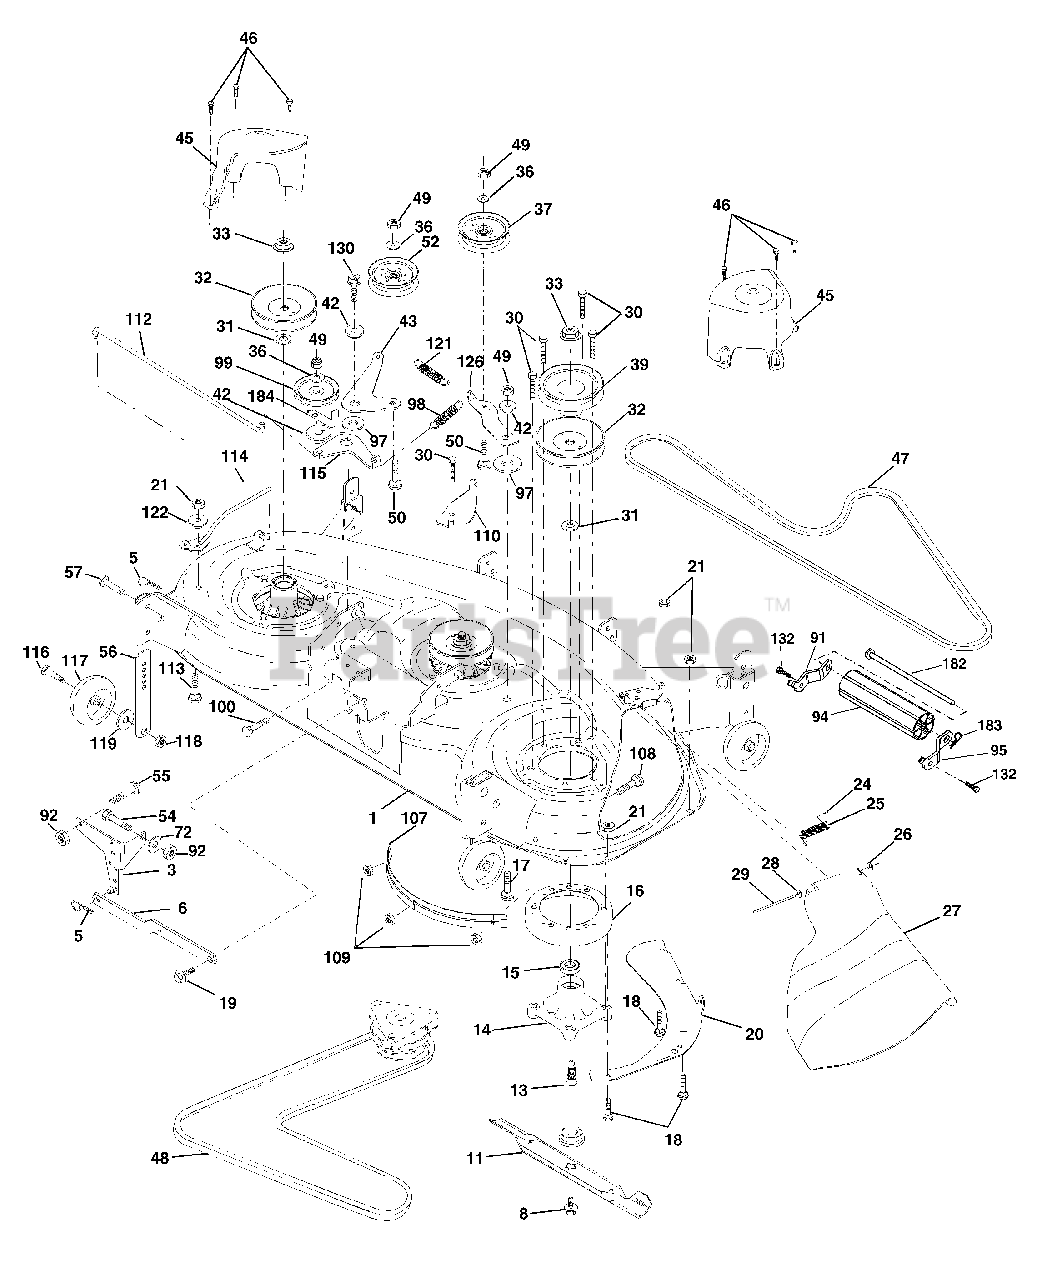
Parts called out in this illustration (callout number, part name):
1	Deck Weldment Mower 48
3	Bracket Asm., Sway Bar
5	Retainer Spring
6	Arm, Suspension, Rear Sway Bar Deck
8	Bolt 7/16 Asm. Blade
11	Blade
13	Shaft Asm. w/Lower Bearing
14	Mandrel Asm. Housing
15	Bearing, Ball, Mandrel
16	Stripper Mandrel Deck
17	Bolt RDHD Sq Neck 3/8-16 x 1.25
18	Bolt, Carriage 5/16-18 x 5/8
19	Bolt, Hex Hd, Shoulder 5/16-18
20	Baffle, Vortex Mower
21	Nut, Crownlock 5/16-18 UNC
24	Cap, Sleeve
25	Spring, Torsion
26	Nut, Push
27	Deflector Shield
28	Washer 11/32 x 5/8 x 16 Ga.
29	Rod, Hinge
30	Screw, Thdroll Washer Head
31	Washer, Spacer Mower Vented
32	Pulley, Mandrel
33	Nut, Flg. Top Lock Cntr. 9/16
36	Washer 13/32 x 13/16 x 16 Ga.
37	Pulley, Idler, Flat
39	Pulley, Idler, Driven
42	Spacer, Retainer
43	Arm, Idler Secondary
45	Cover, Mandrel Deck
46	Screw, Thdroll. 1/4-20 x 5/8
47	V-Belt, Mower, Secondary
48	V-Belt, Mower, Primary
49	Nut, Crownlock 3/8-16 UNC
50	Bolt, Carr. 3/8-16 x 1-1/2 Gr. 5
52	Pulley Idler Flat
54	Bolt Fin Hex 3/8-16 x 1
55	Bolt Carriage Sqnk. 3/8-16 x 1
56	Bar Pnt Adj.
57	Pin Head Rivet
72	Washer 13/32 x 13/16 x 12 Ga.
91	Bracket, Asm Noseroller, LH
92	Nut Lock Hex 3/8-16
94	Noseroller
95	Bracket, Asm Noseroller RH
97	Washer Hardened
98	Spring Primary Drive
99	Pulley Idler"V"
100	Bolt RDHD Sqnk 3/8-16 UNC x 2
107	Baffle Vac Edge Mower
108	Bolt RDHD Sqnk 1/4-20 x 1/2
109	Nut Crownlock 1/4-20
110	Arm Spring Secondary
112	Link Tension Relief Lever
113	Bolt Carr. 5/16-18 x 1
114	Tension Asm. Relief Lever
115	Arm Spring Tension Relief
116	Bolt, Shoulder
117	Gauge Wheel
118	Nut, Centerlock 3/8-16 UNC
119	Washer 3/8 x 7/8 x 14 Ga.
121	Spring Secondary Drive
122	Bushing Pivot Tension Relief
126	Arm, Idler, Primary Deck
130	Screw 3/8-16 x 1.0
132	Screw 3/8-16 x .75
182	Rod Roller Nose
183	Retainer Spring
184	Keeper Belt Idler
